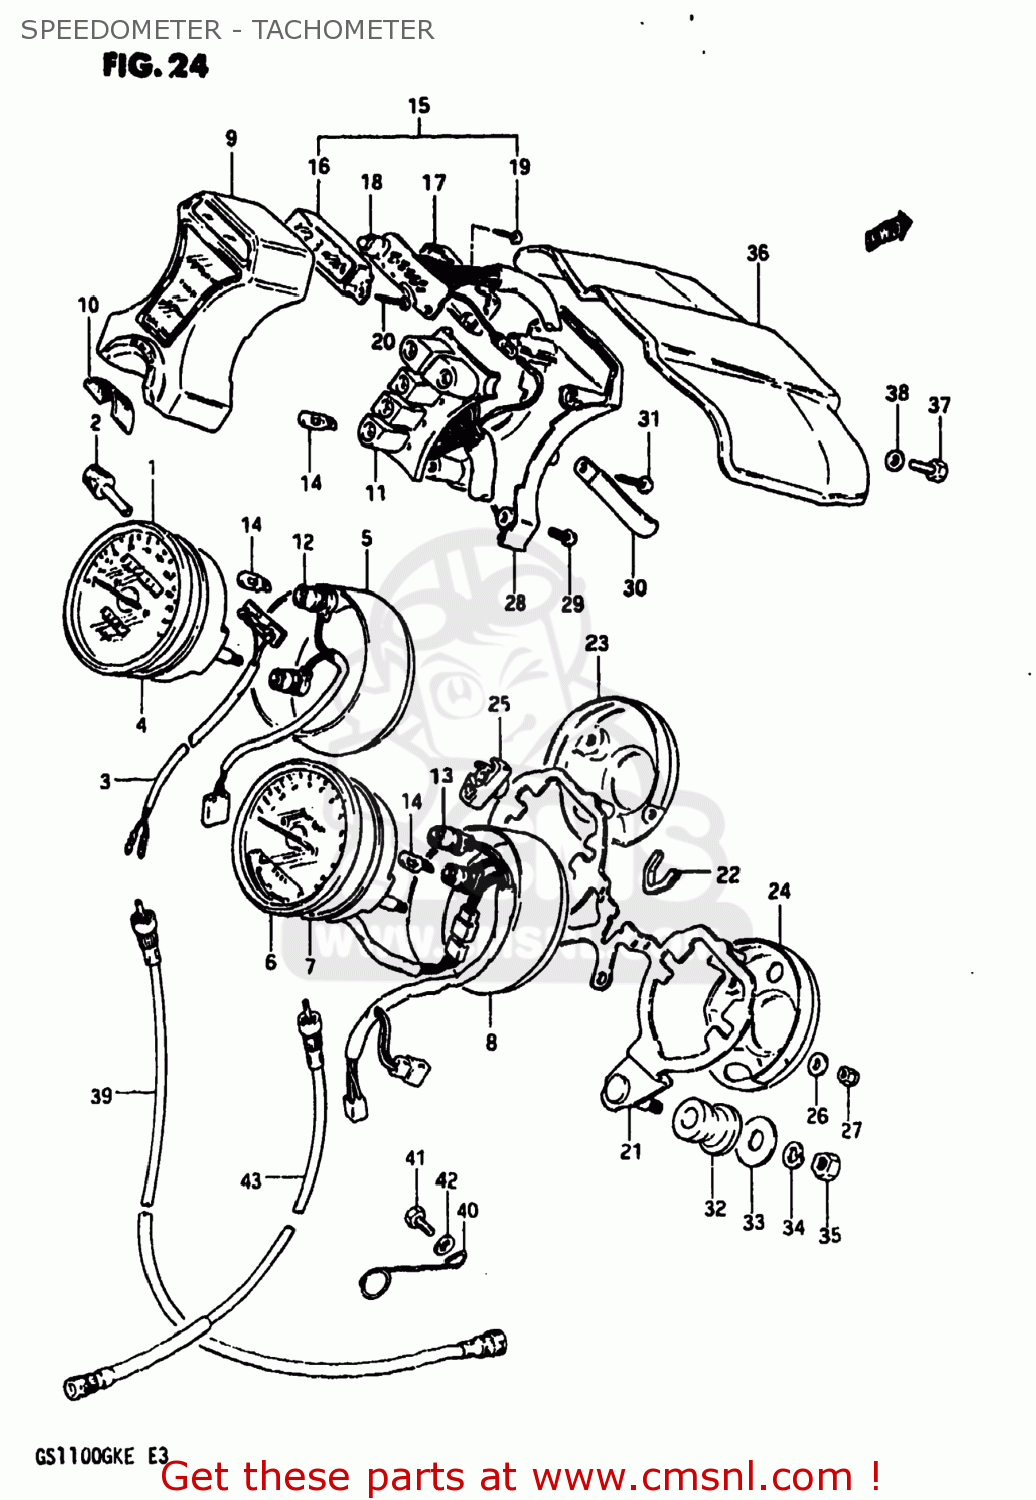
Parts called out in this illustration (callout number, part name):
1	METER,SPEEDOMETER (KM/MPH)
2	KNOB,TRIP
3	WIRE,LEAD SWITCH
4	CUSHION,METER
5	COVER,SPEEDOMETER
6	TACHOMETER
7	CUSHION,METER
8	COVER,TACHOMETER
9	CASE,PILOT BOX
10	SEAL,IGNITION SWITCH
11	SOCKET
12	SOCKET,SPEEDOMETER
13	SOCKET,TACHOMETER
14	BULB(12V3.4W,T10)
15	INDICATOR ASSEMBLY,GEAR POSITION
16	CASE,GEAR INDICATOR
17	COVER,LWR
18	BULB(14V1.12W,BQ041-32503B)
19	SCREW,GEAR INDICATOR
20	SCREW
21	BRACKET,METER
22	BRACKET,COVER
23	COVER,METER,UNDER
24	COVER,TACHOMETER,UNDER
25	CUSHION
26	WASHER
27	NUT
28	COVER,PILOT BOX
29	SCREW,PILOT BULB CASE
30	CLAMP,CORD
31	CROSS SCREW (4X8)
32	CUSHION,METER BRACKET
33	WASHER (8.5X20X1.6)
34	LOCK WASHER
35	NUT
36	HOOD,METER
37	BOLT
38	WASHER
39	CABLE ASSEMBLY,SPEEDOMETER
40	CLAMP,SPEEDOMETER CABLE
41	BOLT, UPPER
42	WASHER
43	CABLE ASSEMBLY,TACHOMETER
